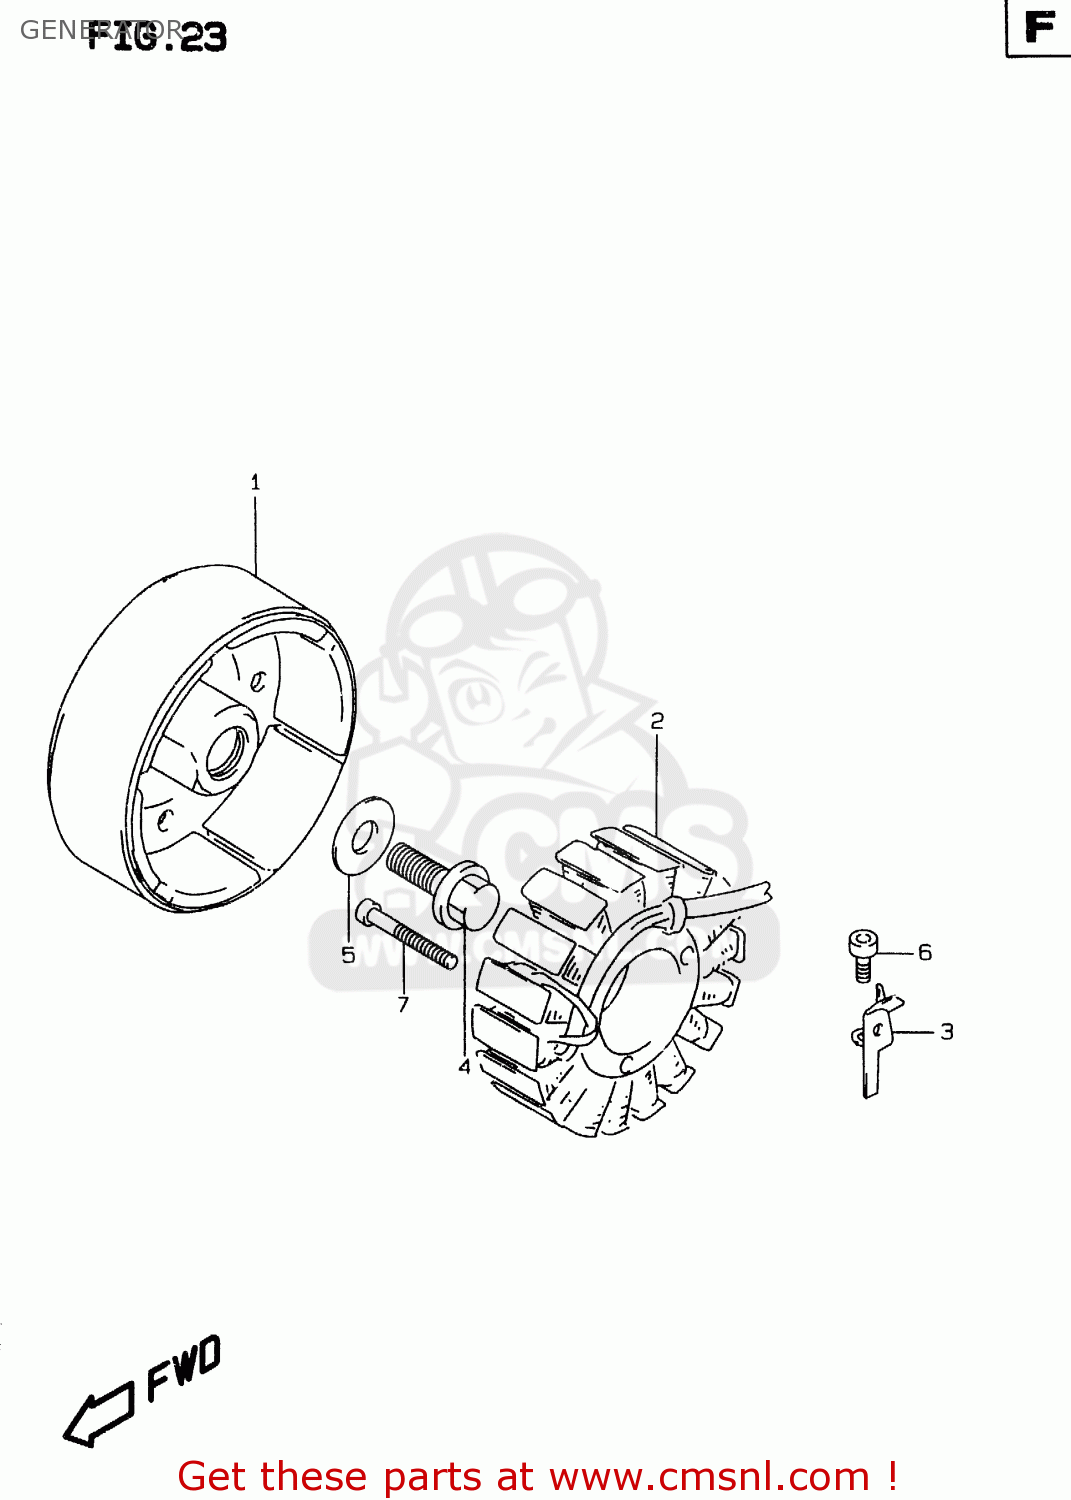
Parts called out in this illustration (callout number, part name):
1	ROTOR ASSY
2	STARTER ASSY
3	CLAMP,MAGNETO LEAD
4	BOLT(12X30)
5	WASHER(12X30X3)
6	BOLT,VAC.PIPE
7	BOLT
